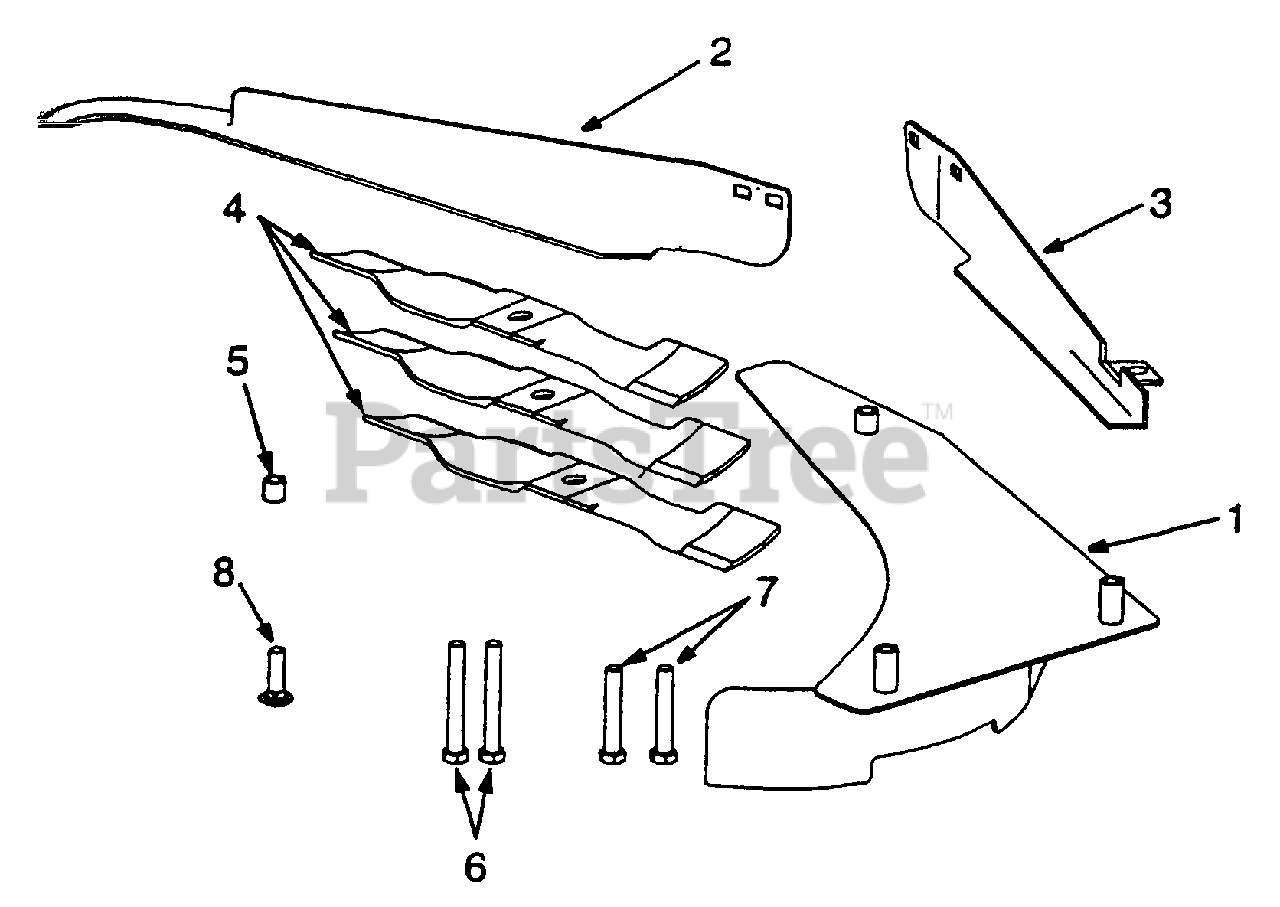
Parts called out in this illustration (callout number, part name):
1	Baffle Ass'y, 48" Mulching
2	Baffle, LH 48"
3	Baffle, RH 48"
4	Blade, Mulching, 16.5 Lg
5	Spacer, .39 ID x .630 OD x 1.1 LG.
6	Screw, Hex Cap, 3/8-16 x 2.25 GR5
7	Screw, Hex Cap, 3/8-16 x 1.75
8	Bolt, Carriage, 3/8-16 x .75 GR5
